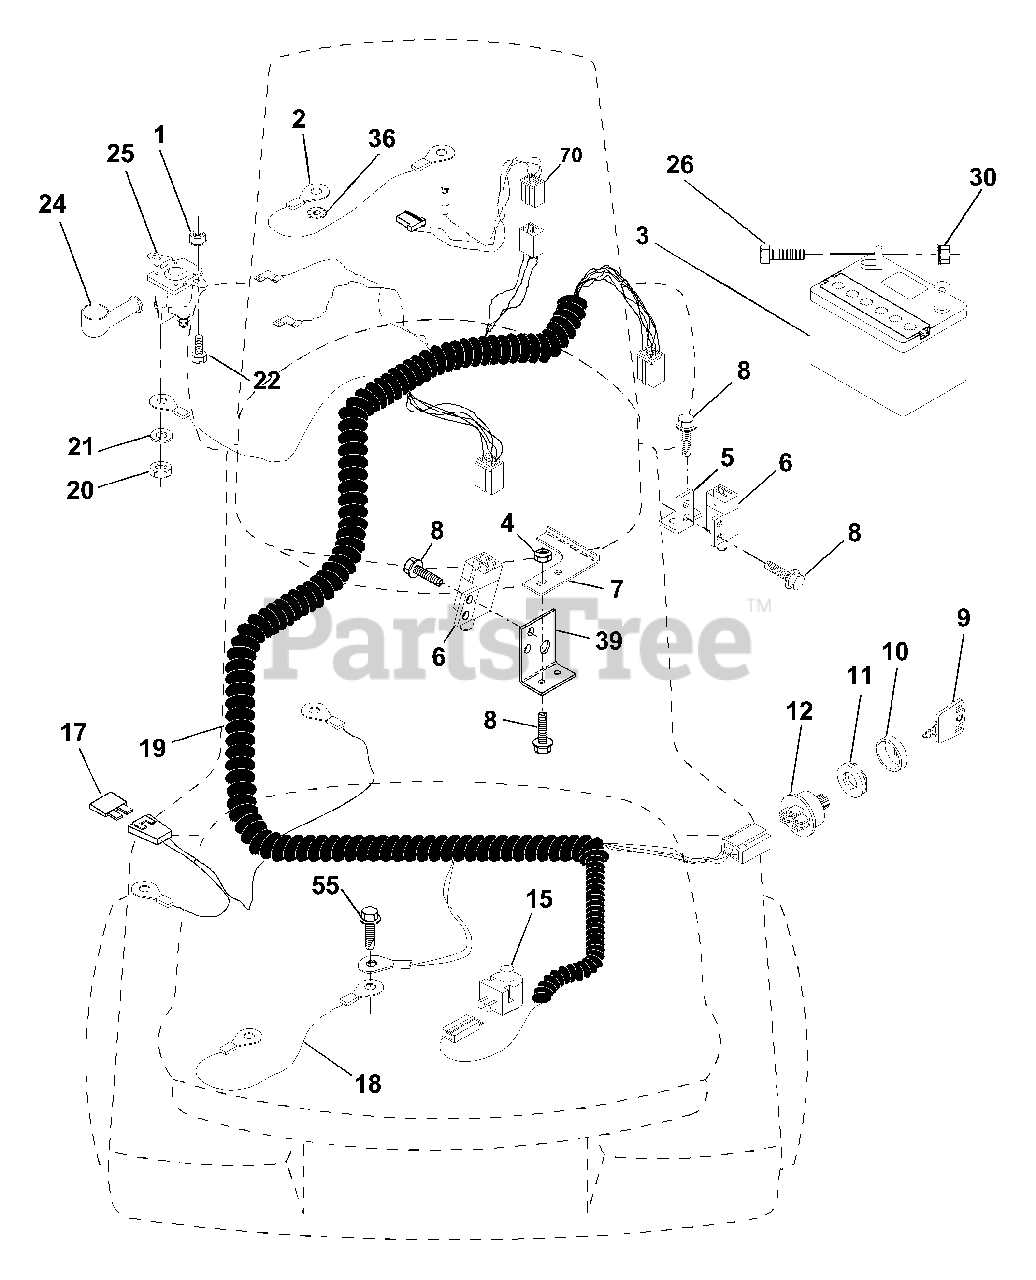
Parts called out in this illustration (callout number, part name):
1	Nut, Hex Keps 1/4-20
2	Assembly, Cable
3	Battery
4	Nut, Lock #10-24 UNC
5	Bracket, Switch
6	Switch, Interlock (4-terminal)
7	Keeper Actuator
8	Screw, Hex Hd. Tap #10-24 x 1/2
9	Key, Steel Delta
10	Cover, Key Ignition
11	Nut, Ignition
12	Switch, Ignition
15	Switch, Plunger
17	Fuse
18	Assembly, Cable
19	Harness, Ignition
20	Nut, Hex Jam 1/4-20
21	Washer, Lock 1/4
22	Bolt, Fin. Hex 1/4-20 UNC x 1/2 Gr. 5
24	Cover, Terminal
25	Solenoid
26	Bolt, Hex Hd. 1/4-20 UNC x 3/4
30	Nut, Keps Hex 1/4-20 UNC
36	Washer, Lock Inter. Tooth 1/4
39	Bracket, Switch Clutch
55	Screw Thdrol 5/16-18 x 1/2
70	Harness, Engine
